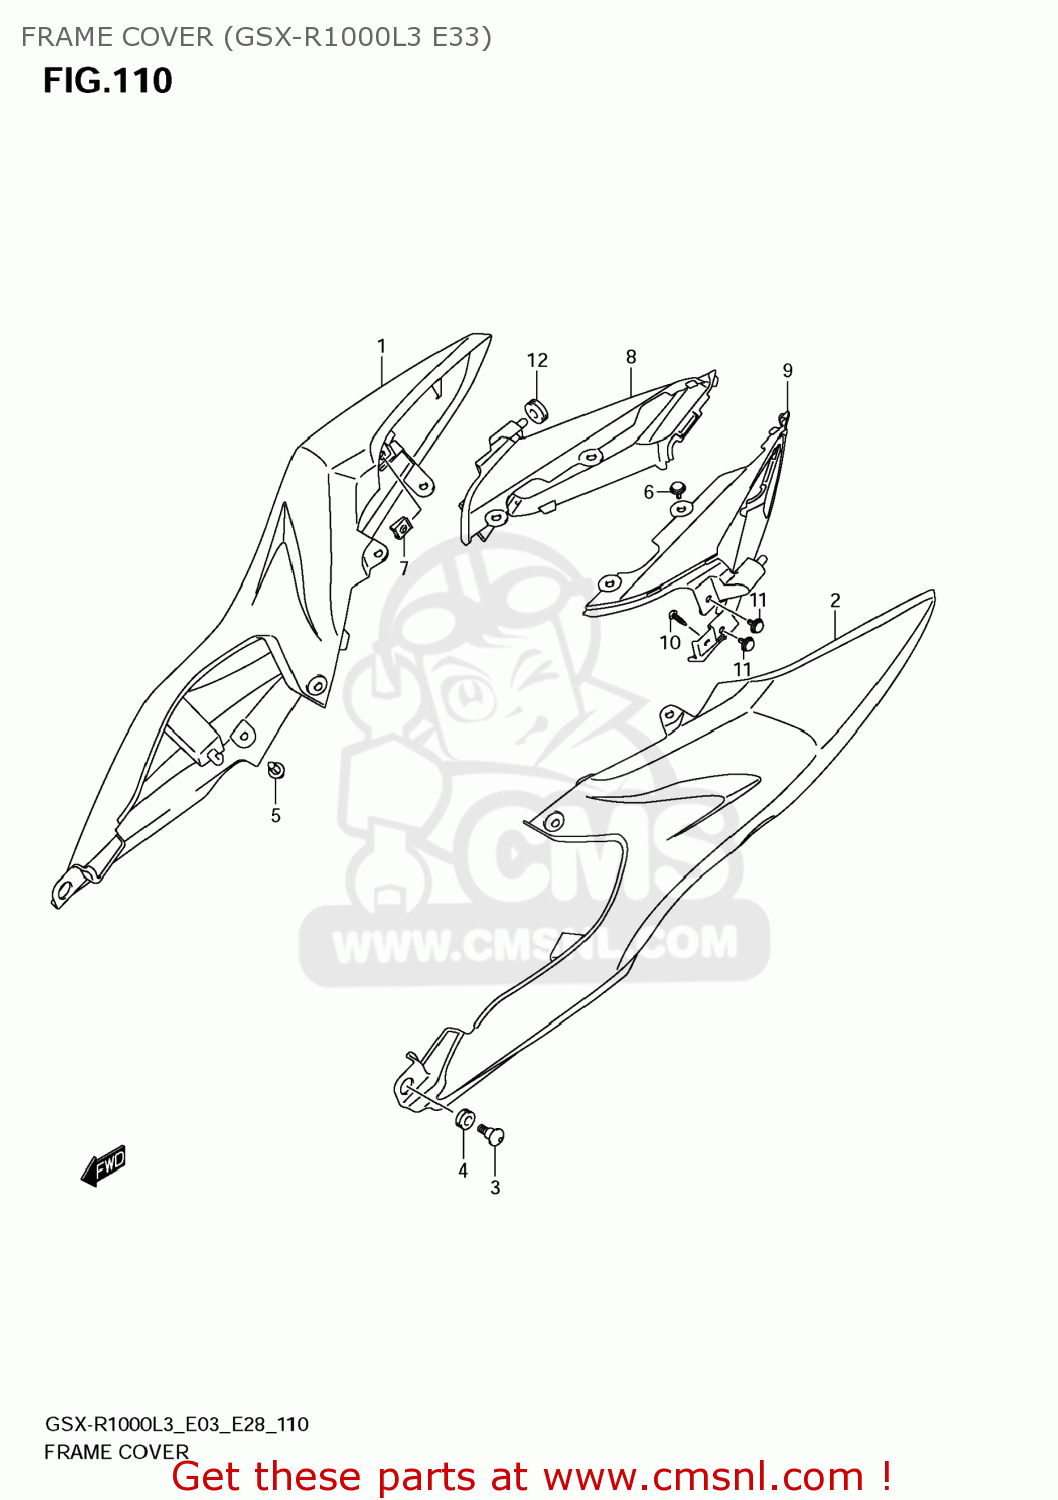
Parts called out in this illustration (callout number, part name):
1	COVER,FRAME,R(WHITE)
2	COVER,FRAME,L(WHITE)
3	SCREW,SIDE COVER LWR,R
4	CUSHION
5	CLIP(BLACK)
6	CLIP
7	NUT
8	COVER,FRAME RR,R
9	COVER,FRAME RR,L
10	SCREW
11	CLIP
12	CUSHION
